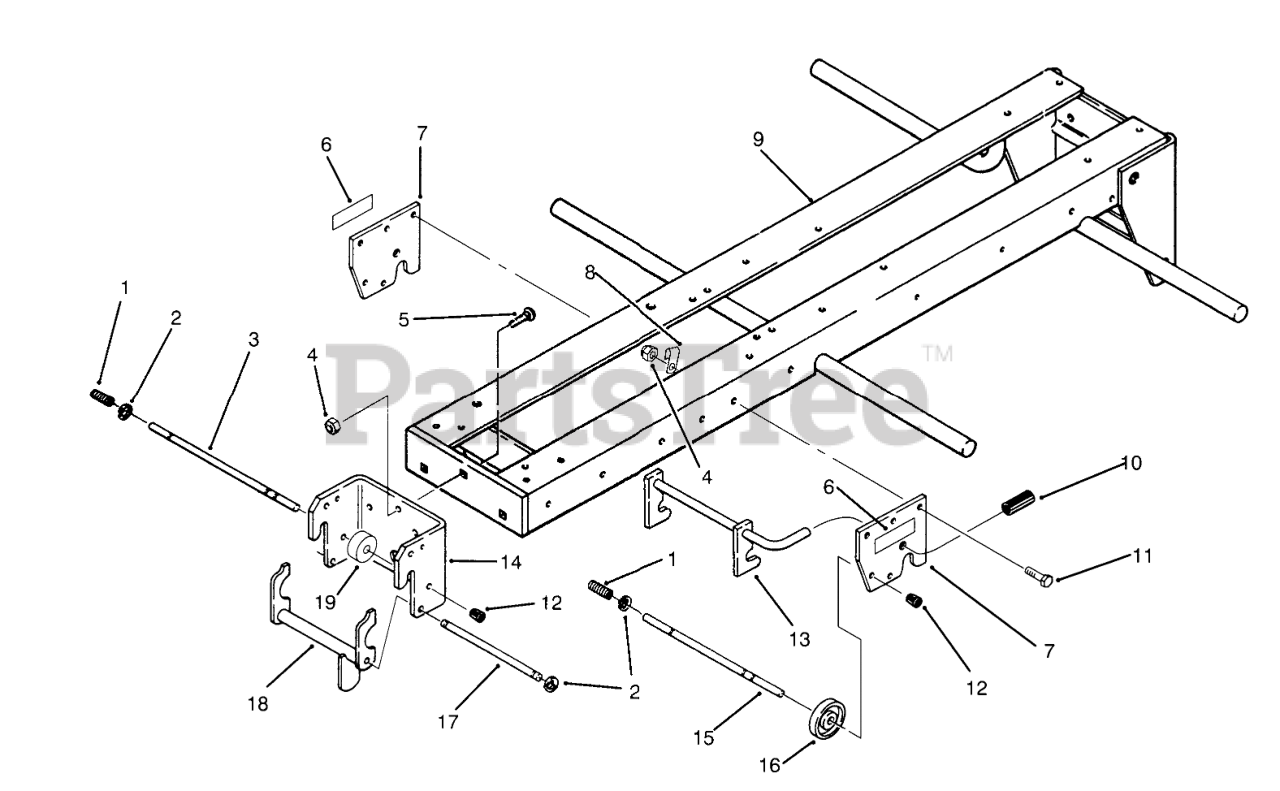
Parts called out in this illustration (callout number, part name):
1	SPRING
2	RING-RETAINING
3	ROD-LOCK
4	NUT-LOCK, NI
5	BOLT-CARR
6	DECAL-ATTACH A-MATIC
7	Hitch Plate
8	CLIP
9	WELD FRAME R
10	GRIP
11	SCREW-HH
12	CAP-ROD, PLUNGER
13	MID HITCH ASM
14	Front Hitch
15	ROD-LOCK
17	ROD-LATCH PIVOT
18	LATCH
